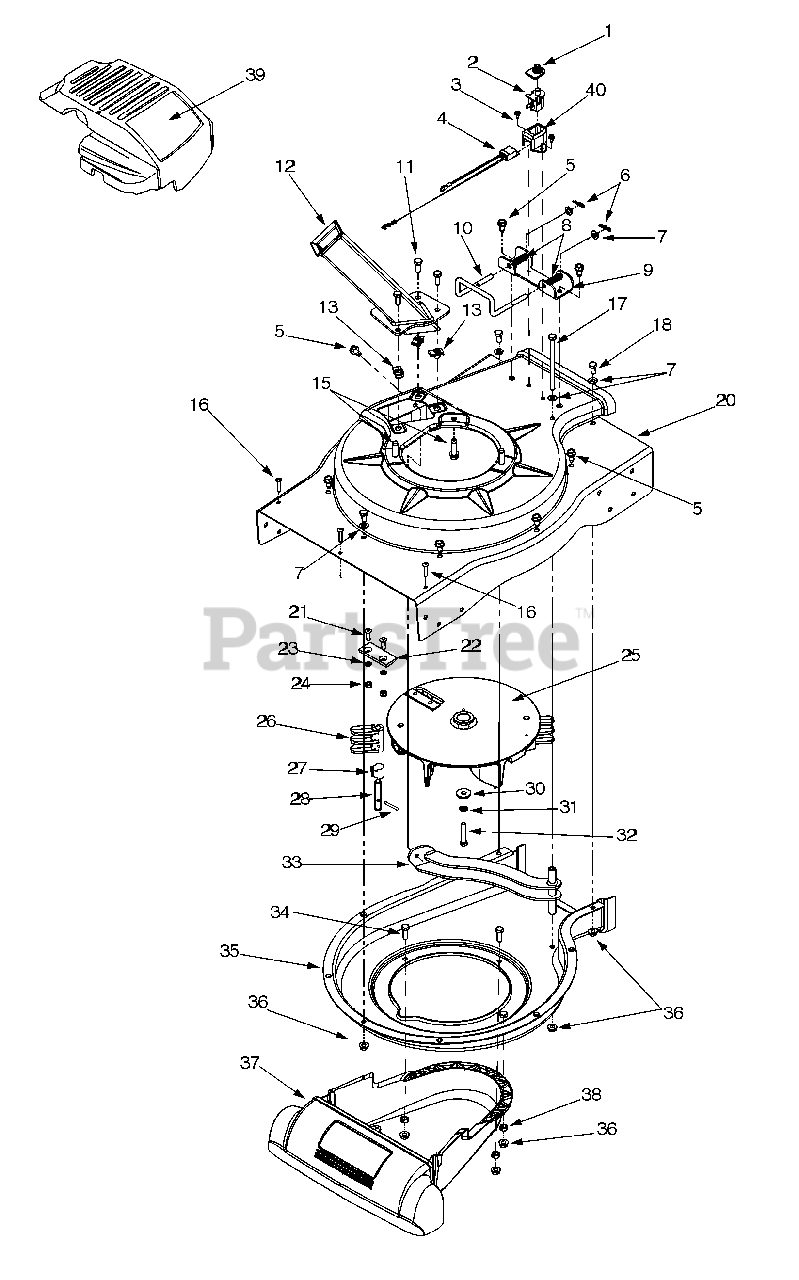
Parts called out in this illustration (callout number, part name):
1	Switch Cover
2	Safety Switch
3	Hex Washer Screw #10-16 x .50
4	Wire Harness
5	Hex Washer Screw 5/16-18 x .625
6	Cotter Pin
7	Flat Washer .330 ID x .630 OD
8	Compression Spring
11	Hex Cap Screw 5/16-18 x .75
13	U-Clip Lock Nut 5/16-18
15	Hex Washer Screw 3/8-16 x 1.25
16	Screw #12-16 x 1.0
17	Hex Cap Screw 5/16-18 x 4.5
18	Hex Cap Screw 5/16-18 x .625
22	Chipper Blade
23	Lock Washer 5/16
24	Hex Lock Nut 5/16-24
25	Impeller Ass'y
26	Flail Blade
28	Clevis Pin
29	Spiral Pin
30	Flat Washer 3/8 ID x 1.25 OD
31	Lock Washer 3/8
32	Hex Cap Screw 3/8-24 x 2.0
34	Hex Cap Screw 5/16-18 x .875
36	Lock Nut 5/16-18
37	Nozzle Cover
38	Lock Nut 5/16-18
40	Safety Switch Cover
